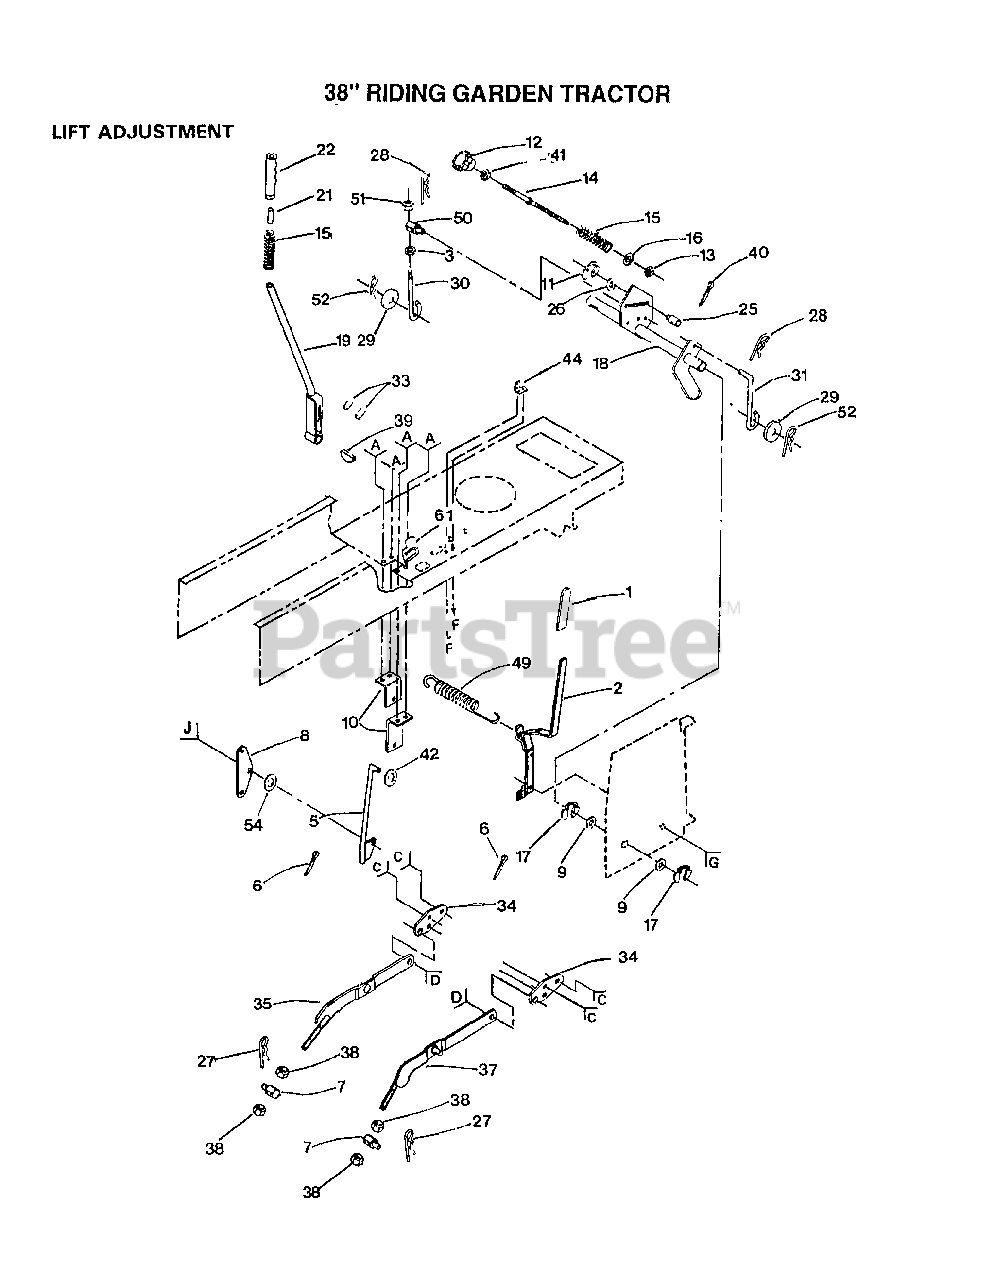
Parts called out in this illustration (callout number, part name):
5	ROD ASSEM YT
6	COTTER PIN
8	"T, BELLCRANK"
9	WASHER
10	"BRKT,BELLCRAN T"
11	KLIP RING
13	NUT T
14	ROD LIFT LT
15	SPRING T
16	WASHER
17	E-RING
22	GRIP
25	TRUNION LT
26	WASHER
27	SPRING H
30	PIVOT PIN T
31	LIFT LINK LT
34	"BRACKET, SUSPE T"
35	LH SUSP ARM ASM
37	RH SUSP ARM ASM
38	NUT
41	NUT
42	WASHER
44	BRACKET LT
49	"SPRING.EXT.8.5"""
51	NUT
52	SPRING.RETAINER
54	WASHER
61	INSUL CLIP T
